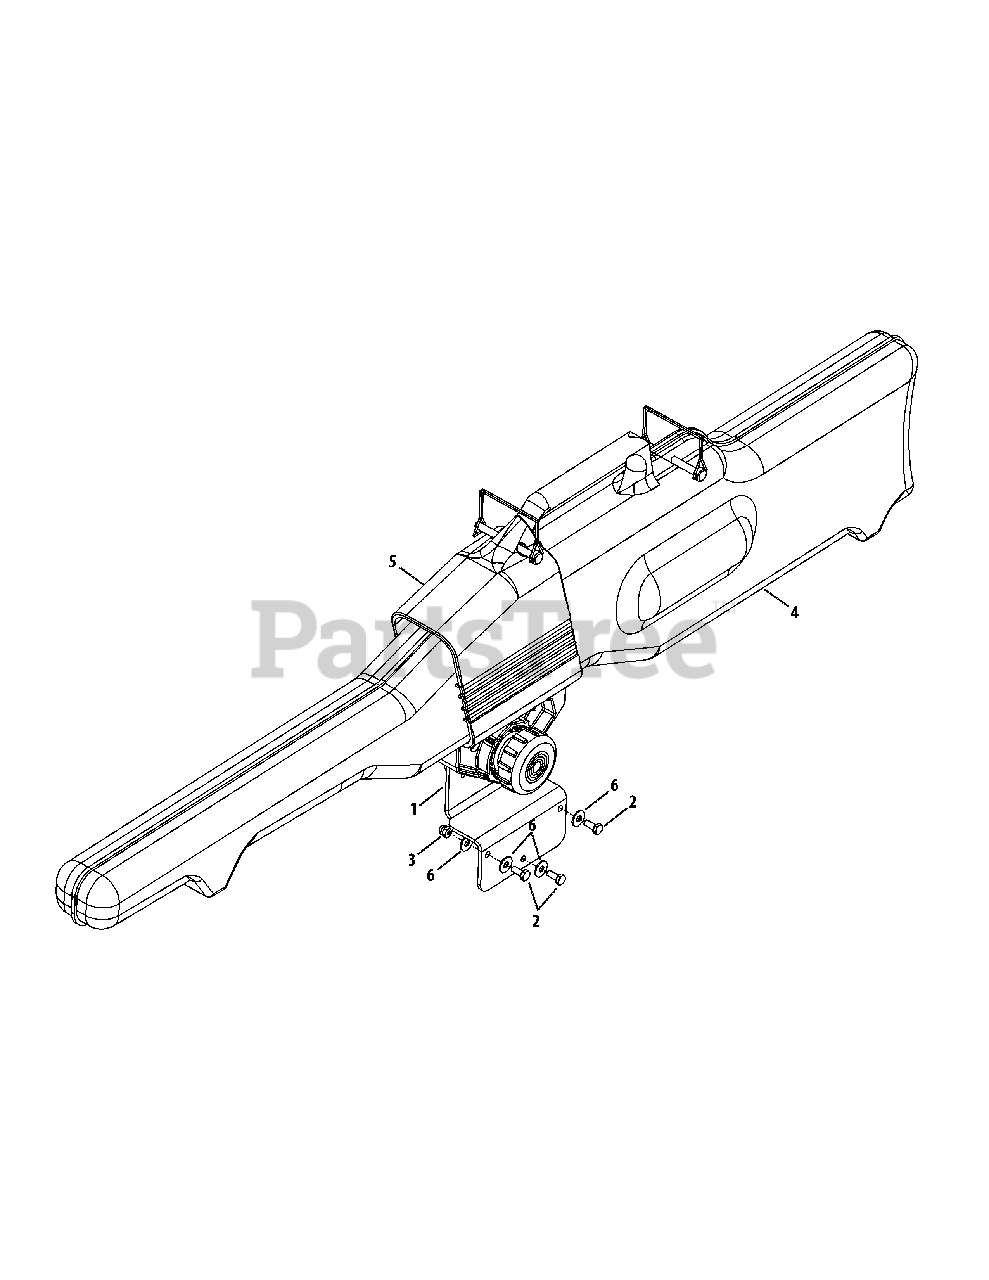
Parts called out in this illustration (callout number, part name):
1	Mnt, Gun Boot
2	Hhcs, 1/4-20 x .620
3	Nut, Acorn, 1/4-20
4	Boot, Gun
5	Mnt, Gunboot
6	Washer, Flat, .28 x .74 x .063
